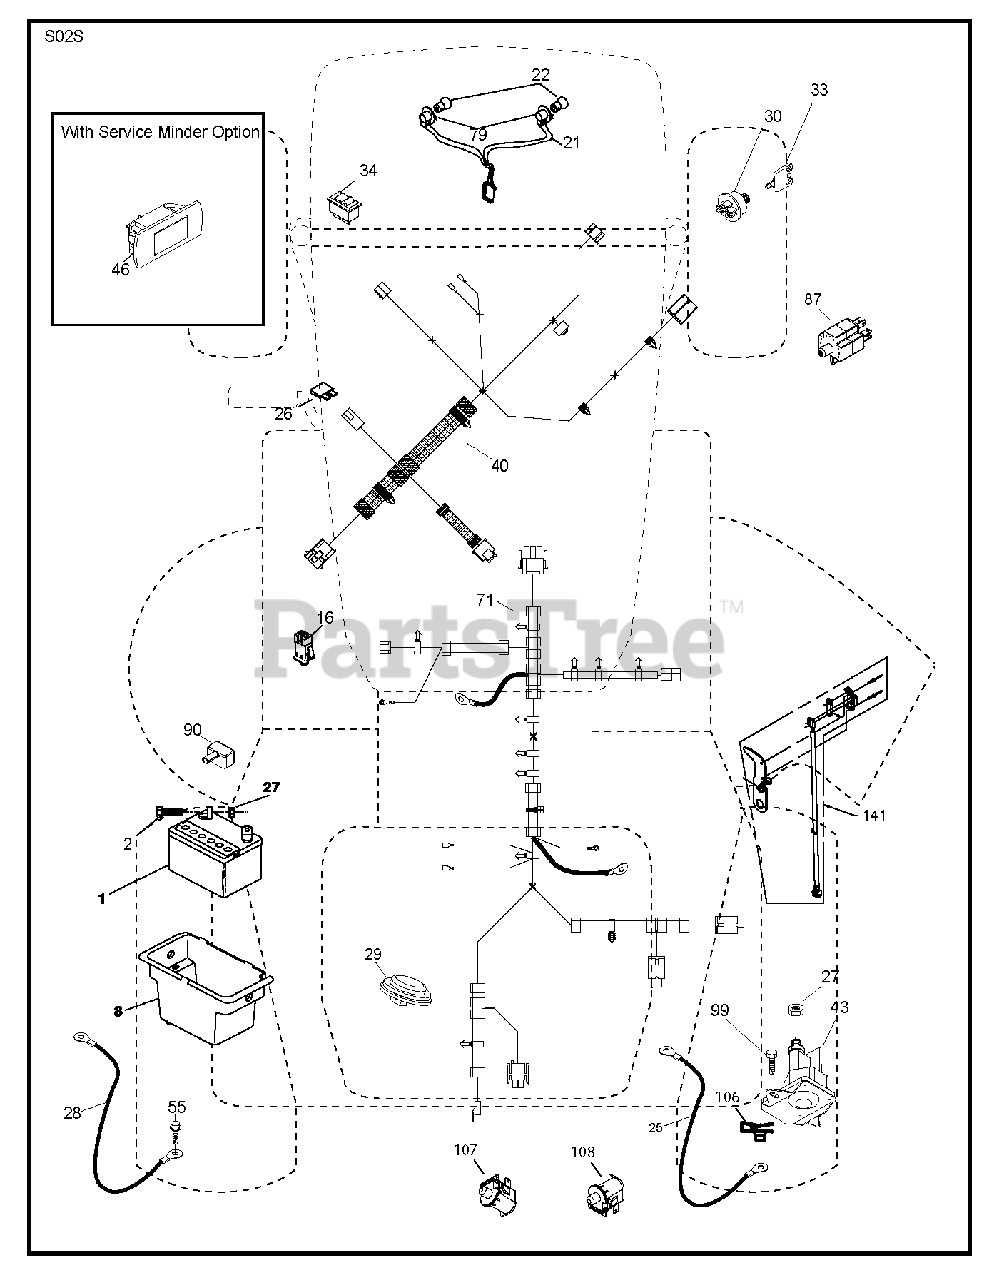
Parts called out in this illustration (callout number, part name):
16	SWITCH INTERLOOK PUSH-IN
21	HARNESS.LIGHT W/4152J BULBS
22	LIGHTBULB
25	CABLE.BATTERY.20.RED.8 AWG
26	FUSE 20AMP
27	NUT
29	SWITCH.SEAT.DELTA.OPC.
30	SWITCH.IGN.DELTA.W.LGH.ROS
33	KEY.CHAIN.BLISTER.PACK.GEN.INT
34	SWITCH LT
43	SOLENOID.W/BRASS.PLUNG
55	SCREW 5/16"
79	BULB HOLDER ASM.
90	COVER.TERMINAL.BATTERY
99	SCREW HEXWSHR 1/4-20X3/4
106	1/4-20 U NUT
108	SWITCH.SNAPMOUNT.NC
141	KIT T2.ROS
